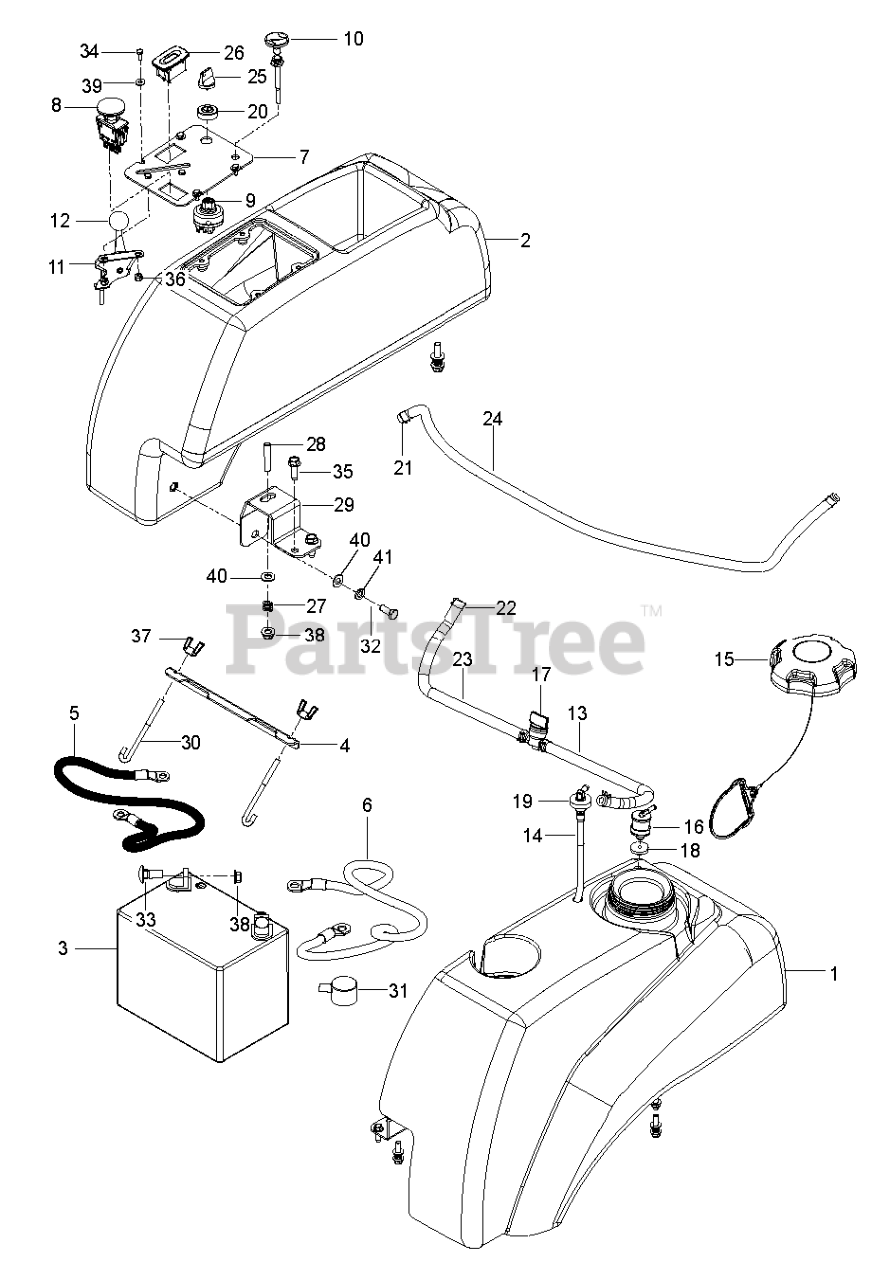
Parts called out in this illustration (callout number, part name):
1	TANK FUEL MZ
2	FENDER CONSOLE
3	BATTERY WET NOT SELLABLE
5	CABLE.GROUND.BATT.MZ.BLACK.39"
6	CABLE.BATT.SOLENOID.MZ.RED.25"
7	PLATE.PNT.CONSOLE.MZ.EDIP
8	RP SWITCH.PTO.TERMINAL.STD.RED
9	SWITCH, IGNITION, INDAK
10	CHOKE CABLE
11	THROTTLE CABLE
12	KNOB.ROUND.BALL.BLACK
13	FUEL.HOSE.SHUT.OFF.ASM.10".10"
14	FITTING, FUEL
15	CAP, FUEL
16	VALVE.FUEL.CHECK
17	FUEL VALVE
18	GROMMET.CHECK.FUEL
19	RUBBER GROMMET
20	CAP IGNITION NUT
21	CLAMP, HOSE
22	HOSE CLAMP
23	HOSE.1/4".LOW.PERM.FUEL.LN.10"
24	HOSE.3/16".VAPOR.LINE.27"LGTH
25	KEY, IGNITION
26	GUAGE.SRVCMNDR.HRMTR.
28	STUD, 5/16C
29	SUPPORT.PNT.TANK.FRONT.STAMPED
31	COVER.TERMINAL.BATTERY
32	HCS 5/16C X 3/4
33	BOLT 5/16C X 3/4" CARRIAGE
34	HCS #10-24 X 1/2
35	SCREW
36	NUT 10-24 NYLOC
37	WING NUT 1/4
38	5/16-18 NYLOC FLANGE NUT
40	WASHER
41	WASHER.LOCK.HVY.HLCL.SPR.5/16
